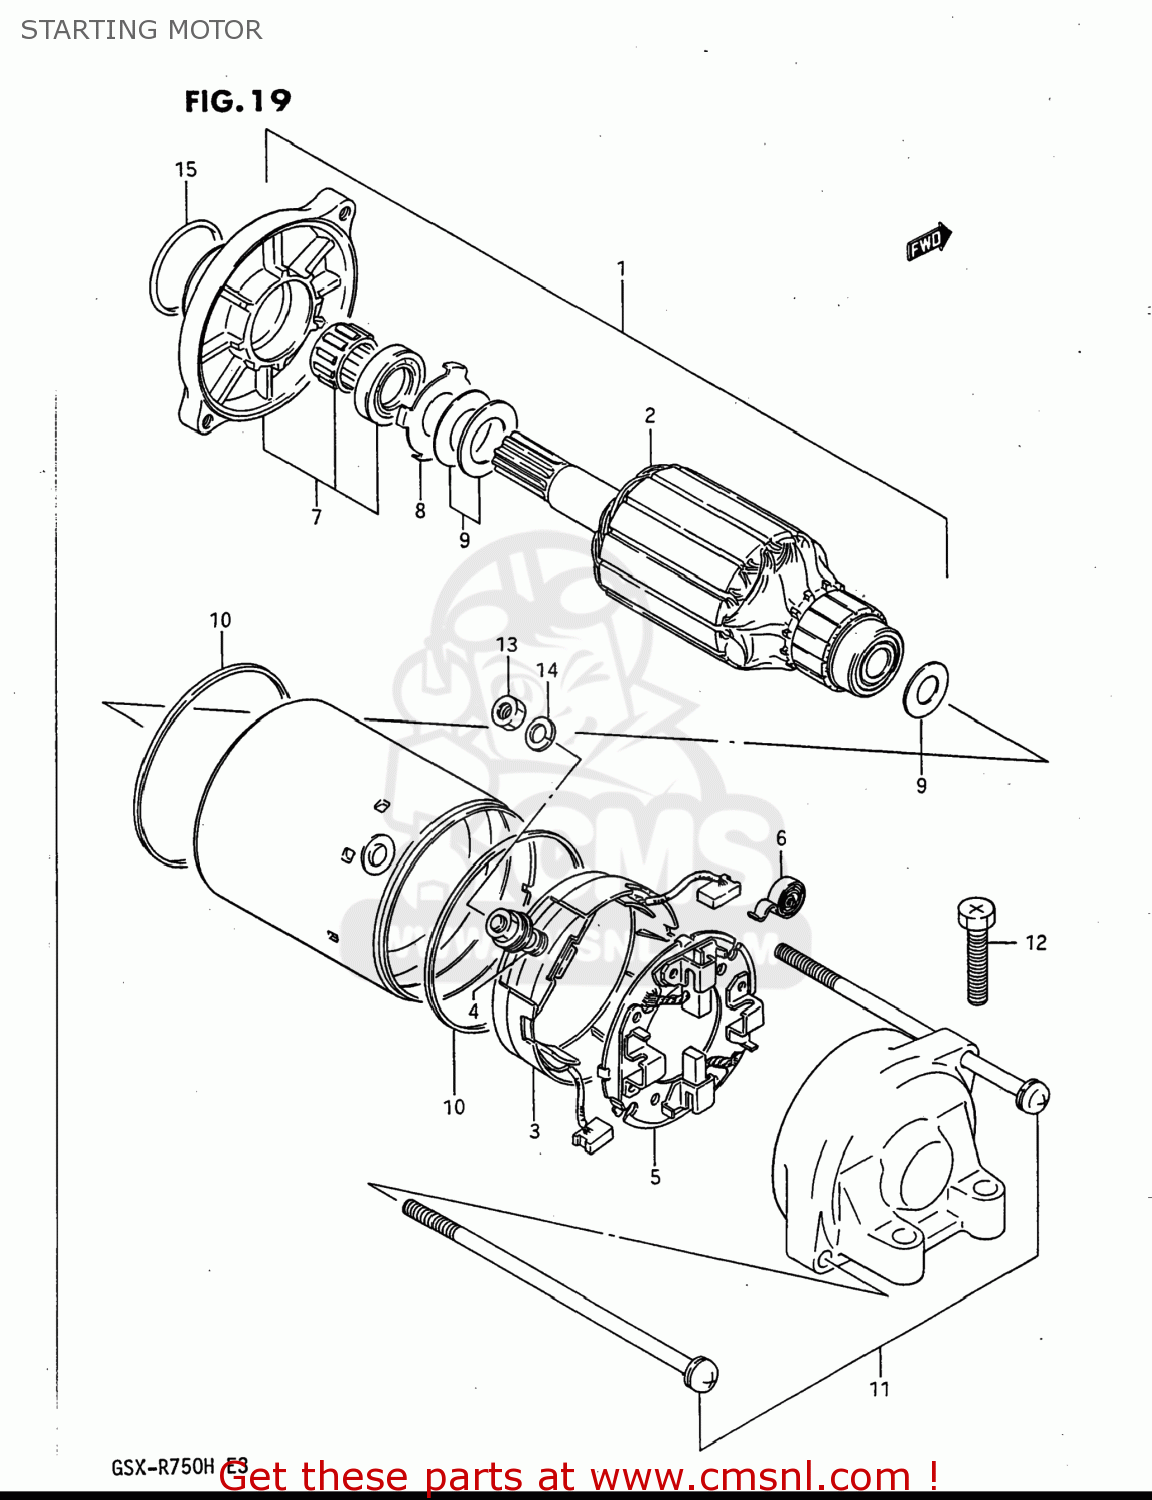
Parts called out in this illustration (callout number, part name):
1	MOTOR ASSY,STARTING
2	ARMATURE
3	TERMINAL SET,BRUSH,PLUS
4	O RING
5	HOLDER SET,BRUSH(-)
6	SPRING,BRUSH
7	BRACKET SET,STARTING MOTOR
8	SHIM SET
9	SHIM SET
10	SEAL,RING
11	BOLT
12	SCREW (6X25)
13	NUT
14	WASHER,LOCK
15	O RING(D:3,ID:24.5)
